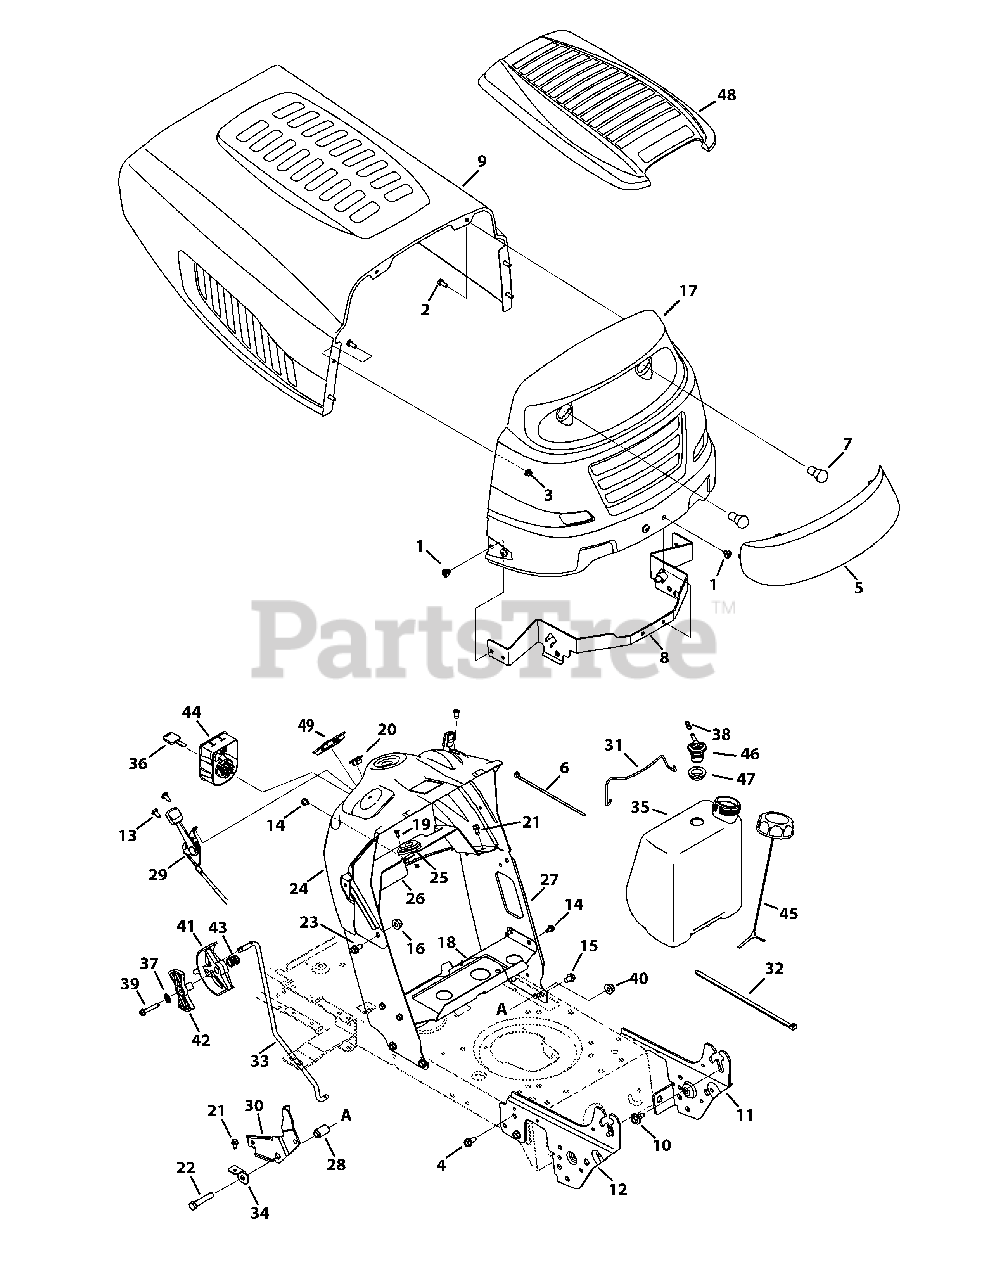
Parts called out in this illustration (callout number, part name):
1	Screw, 5/16-18 x .375
2	Hex Screw, 1/4-20 x .620
3	Flangelock Nut, 1/4-20
4	Screw, 5/16-18 x .750
5	Grill Lens
6	Cable Tie
8	Hood Pivot Bracket
10	Shoulder Screw, 5/16-18 x .43 x .29
11	Left Support Pivot Bracket
12	Right Support Pivot Bracket
13	Screw, 1/4-20 x .500
14	Screw, 1/4-20 x .500
15	Screw, 5/16-18 x .625
16	Flangelock Nut, 5/16-18
18	Gas Tank Support Bracket
19	Screw, #10-16 x .500
20	Choke Plug
21	Tap Screw, 1/4-20, 0.625
22	Hex Screw, 3/8-16 x 2.0
23	Hex Screw, 5/16-18 x .625
24	Dash, Upper
25	Bearing, .628 ID x 1.36
26	Bracket, Steering Support
27	Dash, Lower
28	Flange Spacer, .390 x .671 x 1.095
29	Throttle/Choke Cable
30	Transmission Speed Latch, RMC
31	Battery Assembly Rod
32	Cable Tie
33	Speed Control Rod
34	Speed Latch Tab
35	1.36 Gallon Fuel Tank
36	Key, Assembly
37	Lock Washer, 1/4
38	Hose Vent, 3/16 EPA
39	Hex Washer Screw, 1/4-20 x 1.50
40	Flangelock Nut, 3/8-16
41	Shift Lever
42	Index Control
43	Compr. Spring, .72 OD x .78
44	Key Switch Module
45	Fuel Cap, 2.25"
46	Rollover Valve
47	Rubber Grommet, 23 x 3.55
48	Hood cover
49	Ammeter Plug
